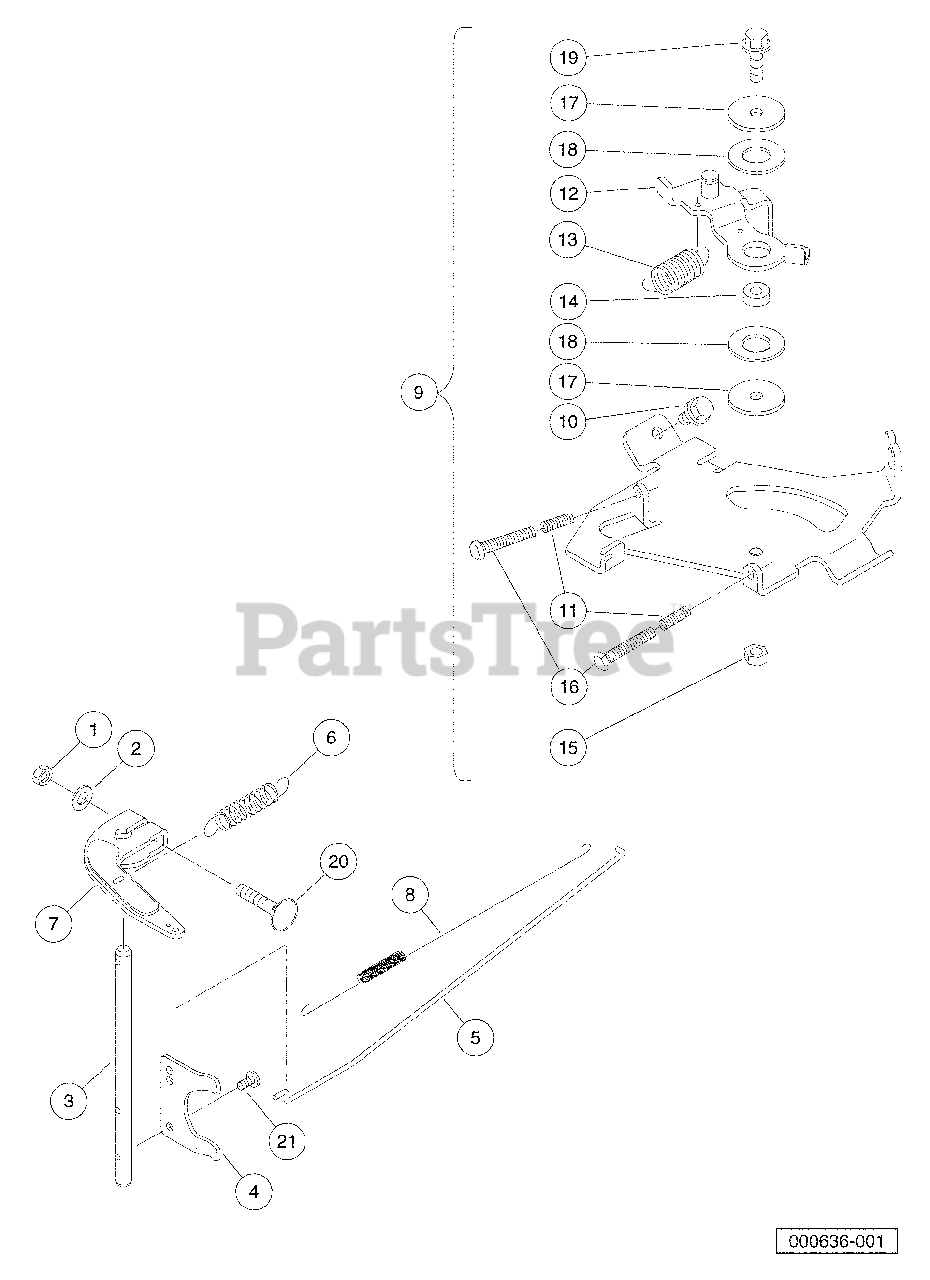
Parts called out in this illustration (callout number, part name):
1	Nut -6mm-.
2	Washer, M6 Flat
3	Shaft, Governor, Fh
4	Plate, Governor, Fh
5	Link, Arm, Governor, Fh
6	Spring, Governor, Fh
7	Arm, Governor, Shaft
8	Spring, Arm, Governor, Fh
9	Panel, Control, Complete, Fh
10	Bolt, Flg, M6 X 1.0 X 12
11	Spring, Fh
12	Lever, Governor, Control, Fh
13	Spring, Governor Return, Fh
14	Collar, Governor, Fh
15	Nut, Governor, Fh
16	Bolt, Speed Control, Fh
17	Washer, Governor, Lower, Fh
18	Washer, Governor, Middle, Fh
19	Bolt, Flanged, M6 X 20, Kaw
20	Bolt, M6 X 35, Kawasaki
21	Screw, Pan, Governor, Fh
